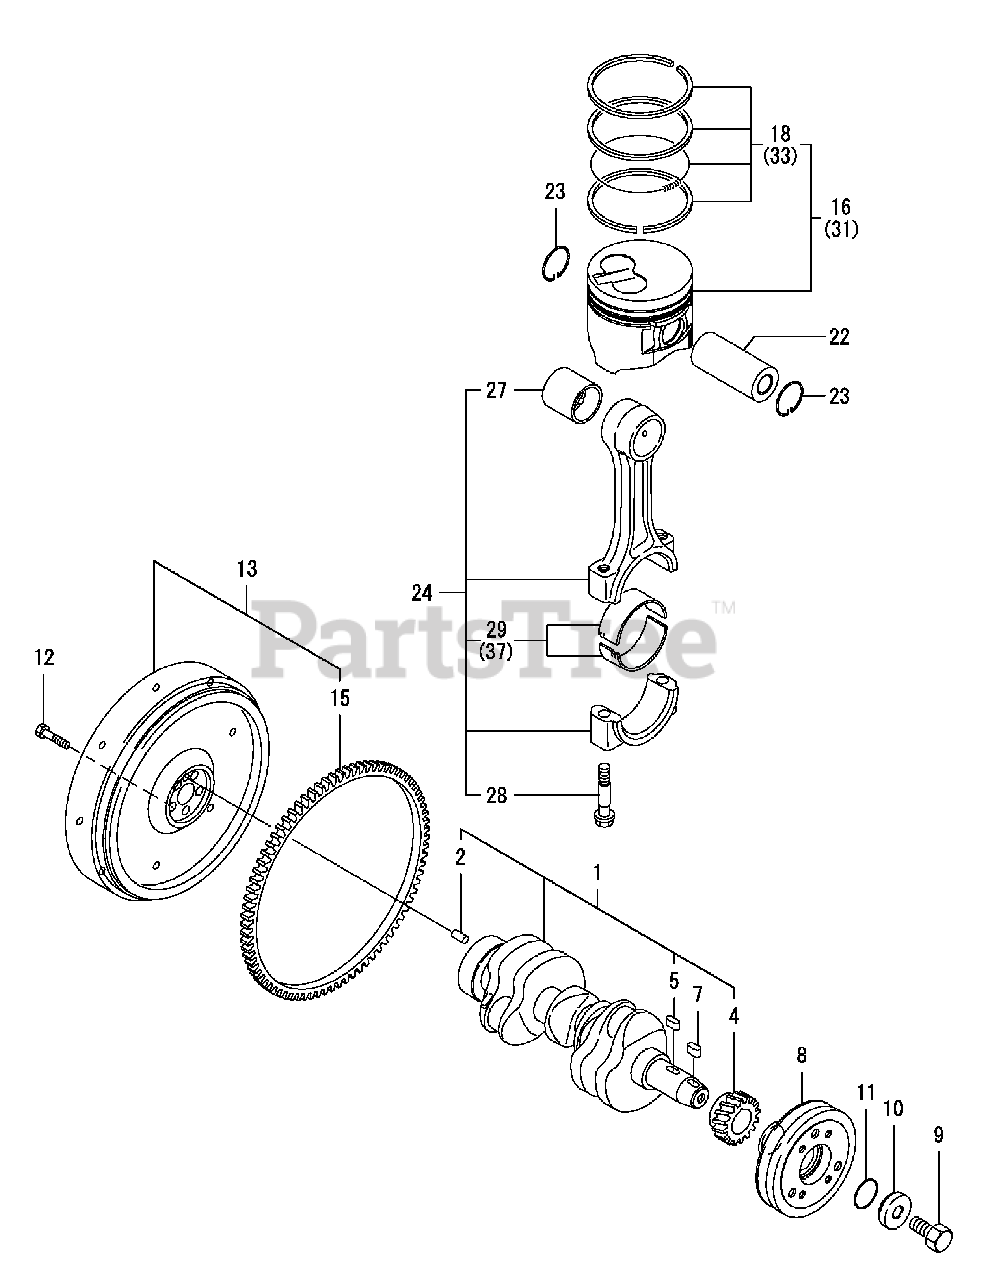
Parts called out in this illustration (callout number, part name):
1	CRANKSHAFT ASSY
2	PARALLEL PIN 8X16
4	GEAR, CRANKSHAFT
8	V-PULLEY, CRANKSHAFT
9	BOLT M12X1.25,FLANGE
11	O-RING 1A S-34.0
12	BOLT, FLYWHEEL
24	ROD ASSY, CONNECTING
27	BUSH, PISTON PIN
28	BOLT, CONNECTING ROD
29	METAL ASSY,CRANK PIN
31	PISTON ASSY(O.S=0.25
33	RING SET (O.S=0.25)
37	BEARING,PIN US=0.25
